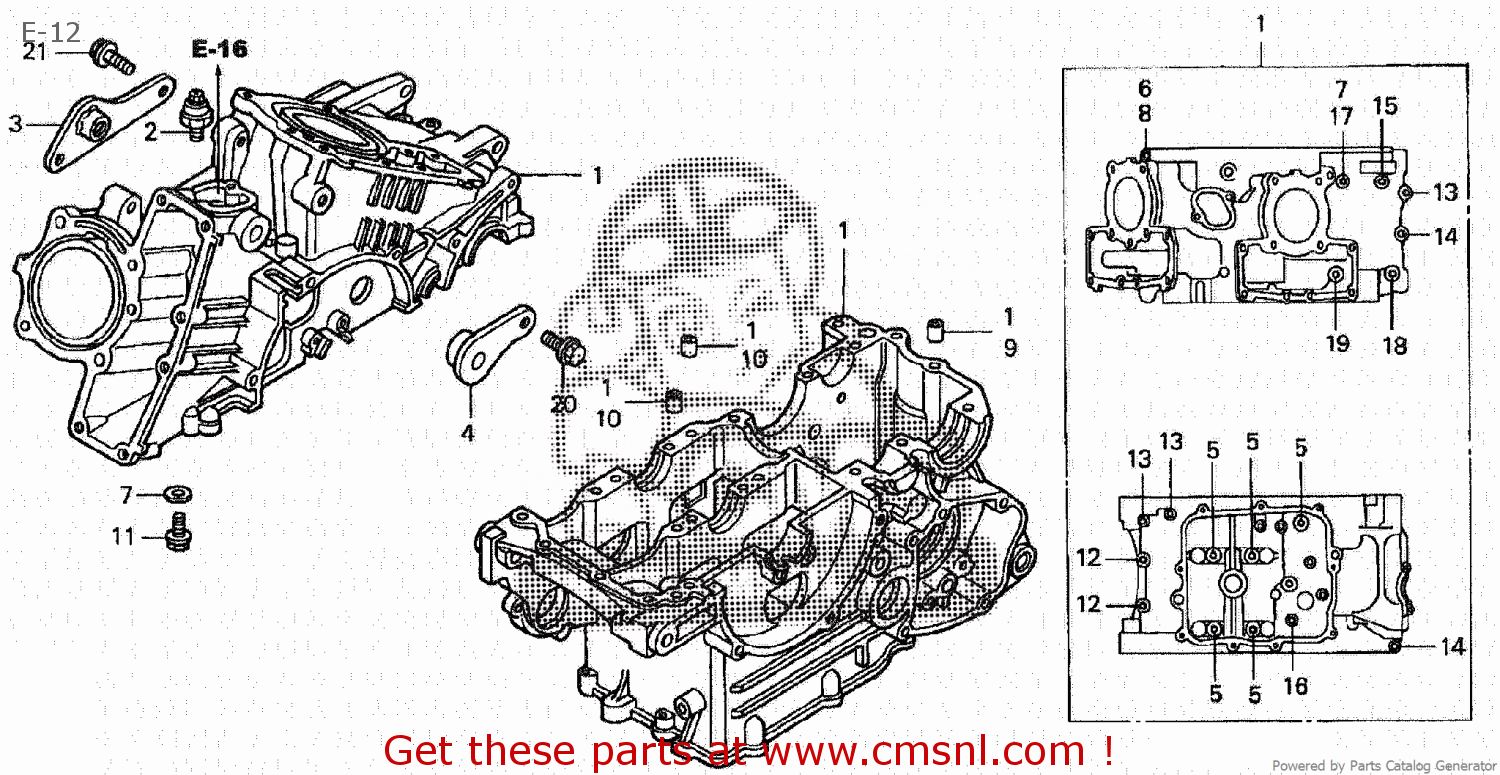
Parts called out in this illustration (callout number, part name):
1	CRNKCS SET(MC15E)
2	SW.ASSY OIL PRESS
3	PLATE R,ENG HANGE
4	PLATE L,ENG HANGE
5	BOLT,UBS,8X75
6	BOLT,SPECIAL,6X45
7	WASHER,SEALING,6.
8	WASHER, BRAKE ARM
10	PIN,KNOCK,8X140
12	BOLT,FLANGE,6X32
13	BOLT,FLANGE,6X40
14	BOLT,FLANGE,6X45
15	BOLT,FLANGE,6X60
16	BOLT,FLANGE,6X70
17	BOLT,FLANGE,6X85
18	BOLT,FLANGE,8X50
19	BOLT,FLANGE,8X65
20	BOLT,FLANGE,10X30
21	BOLT,FLANGE,10X35
